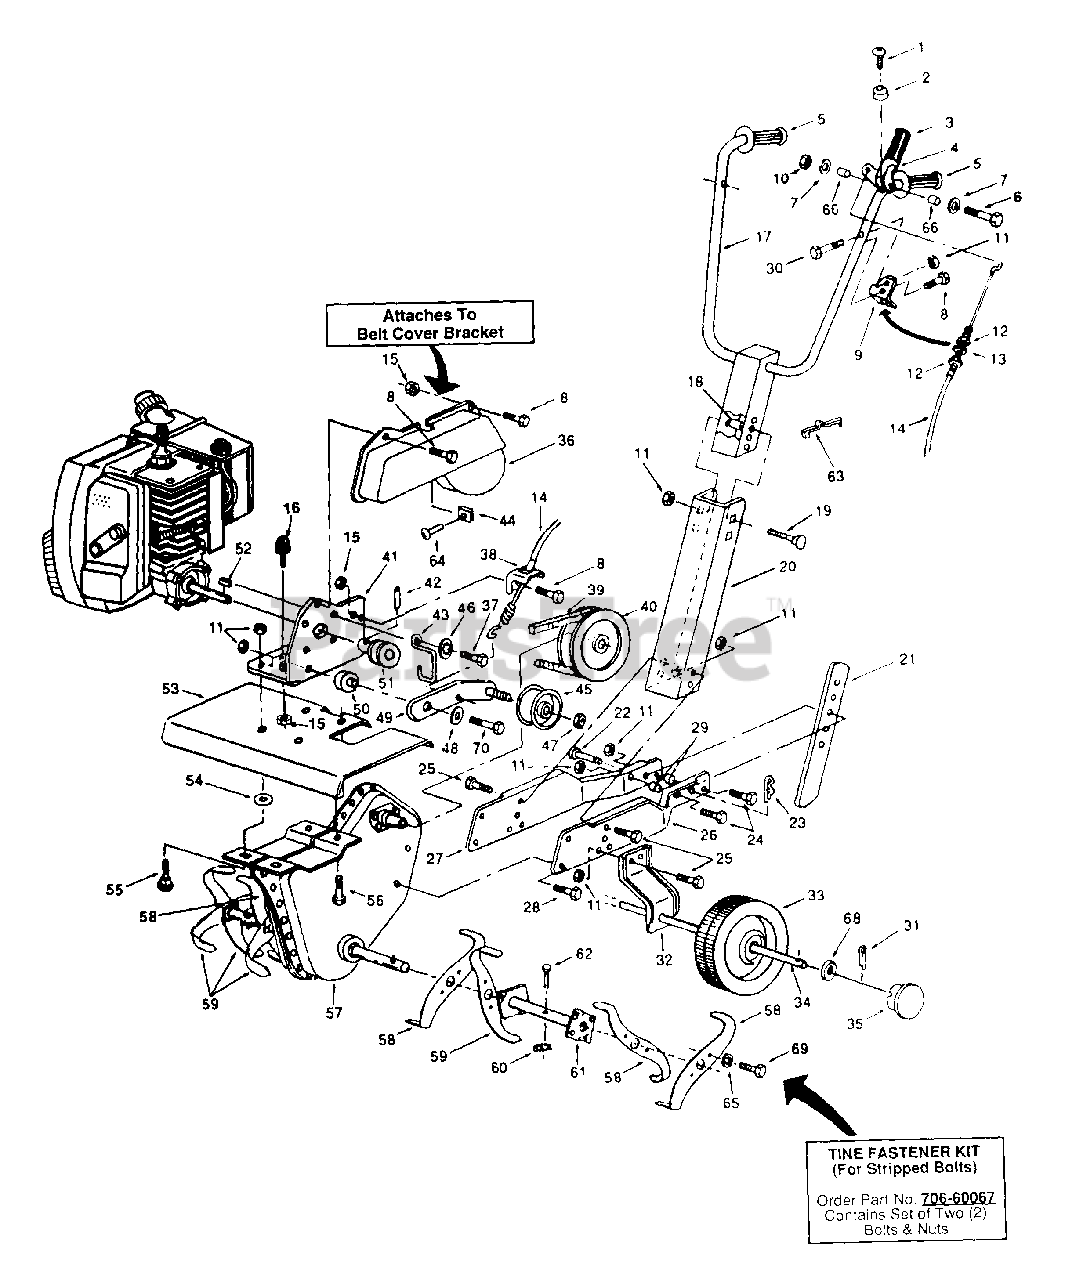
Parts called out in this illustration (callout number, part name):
1	Tap Scr. #10-16 x 1/2
2	Rubber Bumper
3	Vinyl Grip
5	Handle Grip
6	Hex Bolt 1/4-20 x 2"
7	Fl-Wash. 1/4" I.D.
8	Hex Tap Scr. 1/4-20 x 1/2
9	Cable Bracket
10	Lock Nut 1/4-20 Thd.
11	Lock Nut 5/16-18 Thd.
12	Hex Jam Nut 5/16-24 Thd.
13	L-Wash. 5/16" I.D.
14	Clutch Control Cable
15	Hex Sems Nut 1/4-20 Thd.
16	Bumper
19	Carr. Bolt 5/16-18 x 2-1/2"
23	Hairpin Cotter
24	Hex Bolt 5/16-18 x 1"
25	Hex Bolt 5/16-18 x 5/8"
29	Spacer
30	Hex Bolt 5/16-18 x 1-1/4"
31	Cotter Pin
34	Axle - Wheel
35	Hub Cap
36	Belt Cover
37	Hex Bolt 1/4-20 x 5/8"
38	Bracket - Clutch Lever
39	V Belt (Special)
40	Pulley - Chain Case
41	Plate - Engine Mounting
42	Set Screw 5/16-18 x 3/8"
43	Belt Retainer
44	Clip - Tinnerman
45	Flat Idler Pulley
46	Int. L-Wash. 1/4" I.D.
47	Hex Jam L-Nut 3/8-24 Thd.
48	Fl-Wash. 5/16" I.D.
49	Idler Arm Ass'y.
50	Pivot Spacer
51	Engine Pulley
52	Square Key 1/8 x 3/4"
53	Tine Shield (Red)
54	Spacer
55	Carriage Bolt 5/16-18 x 1"
56	Hex Bolt 5/16-18 x 3/4"
57	Chain Case Ass'y. Comp.
58	R.H. Tine Blade
59	L.H. Tine Blade
60	Hairpin Cotter
61	Adapter Ass'y.- Tine
62	Clevis Pin
63	Cable Tie - Plastic
64	Hex Sems Bolt #10-16 x 3/4 Lg.
65	L-Wash. 1/4" I.D.
66	Spacer
68	Fl-Wash. 3/8" I.D.
69	Tap Scr. 1/4-20 x 1/2"
70	Hex Bolt 5/16-18 x 1-1/2"
